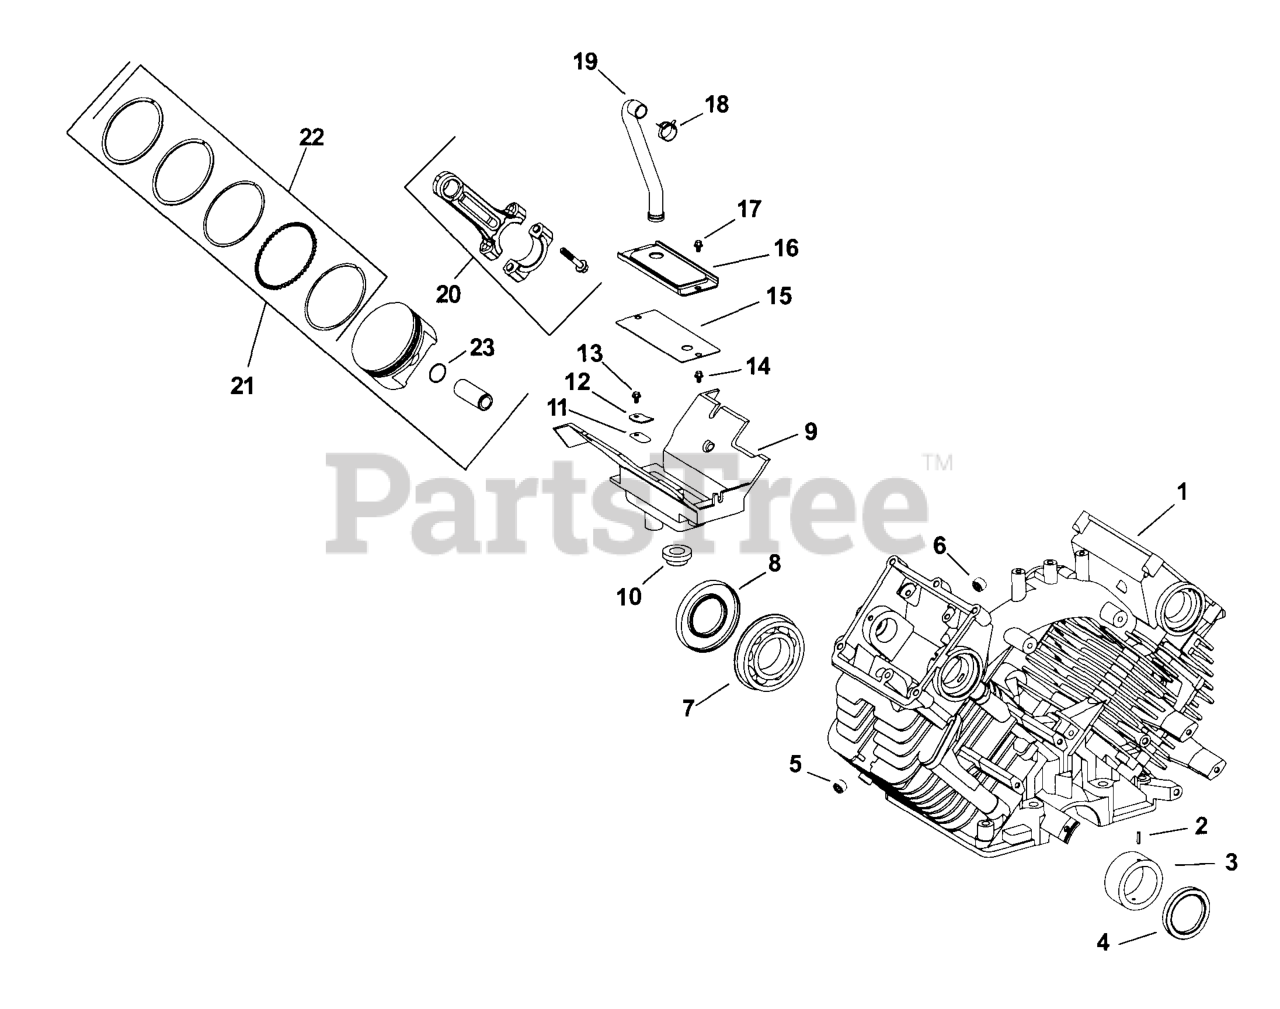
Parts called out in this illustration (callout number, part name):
1	CRANKCASE ASSY-UPPER - DISC
2	PIN, ROLL
3	BEARING, SLEEVE
4	SEAL, OIL
7	BEARING, BALL
8	SEAL, OIL - DISCONTINUED
9	KIT, BREATHER - DISCONTINUED
11	REED, BREATHER
12	RETAINER, REED - DISCONTINUED
13	SCREW, FLG THD FRM M5X.8X10
13	SCREW, THREAD FORMING - DISCONTINUED
14	SCREW, FLG M6X1.0X10
15	GASKET, BREATHER COVER
16	COVER, BREATHER - DISCONTINUED
17	SCREW,FLG THD FRM M6X1.0X16-(#25086397S)
17	SCREW, THREAD FORMING
18	CLAMP, HOSE (KM)-USE 25 237 31-S
19	HOSE, BREATHER
20	ROD, CONNECTING - (#DSC)
20	ROD, CONNECTING - DISC.
21	PISTON W/RING SET (STD) - (#DSC)
22	RING SET, STD - DISCONTINUED
23	RETAINER, PISTON PIN
